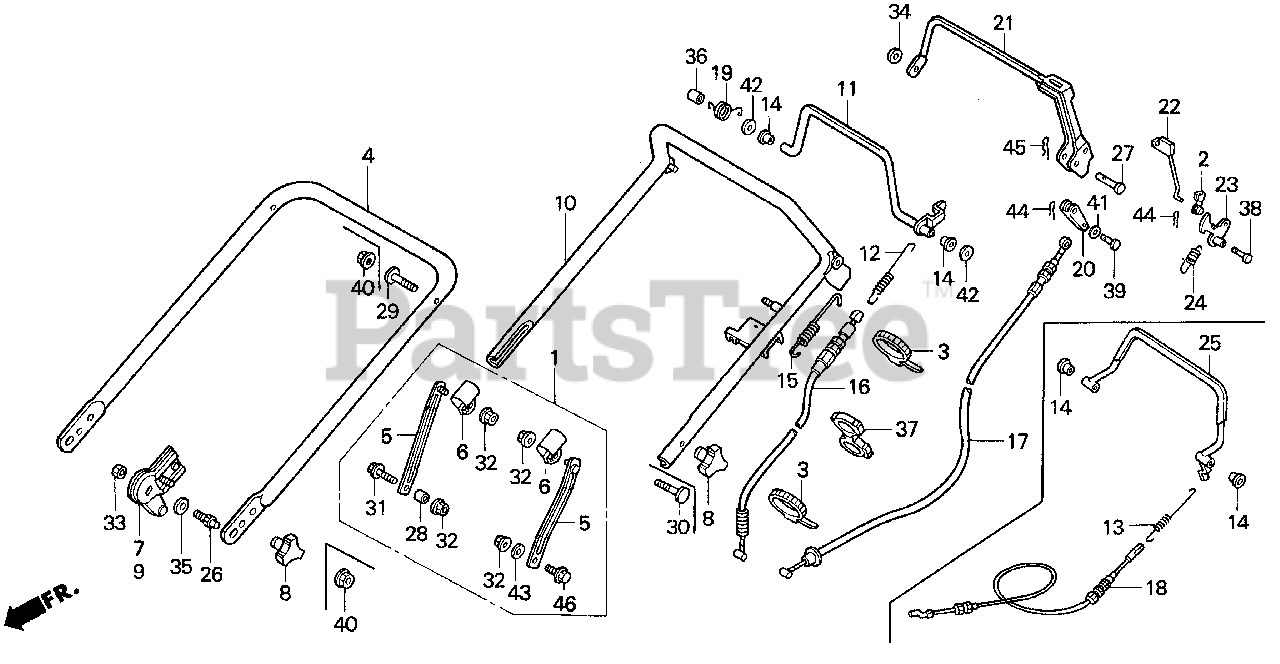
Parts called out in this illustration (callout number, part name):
3	TIE, CABLE
4	PIPE, HANDLE (LOWER)
7	STAY, R. HANDLE *NH190M* (VINTAGE GRAY METALLIC)
9	STAY, L. HANDLE
9	STAY, L. HANDLE *NH190M* (VINTAGE GRAY METALLIC)
10	PIPE, HANDLE (UPPER)
13	SPRING, CLUTCH
14	BUSH, CLUTCH LEVER
18	CABLE, BRAKE
25	LEVER, BRAKE
26	BOLT, HANDLE HOOK
30	BOLT, HANDLE HOLDER
33	NUT, SELF-LOCK (8MM)
35	WASHER, SPECIAL (22X8.5X2)
40	NUT, FLANGE (8MM)
